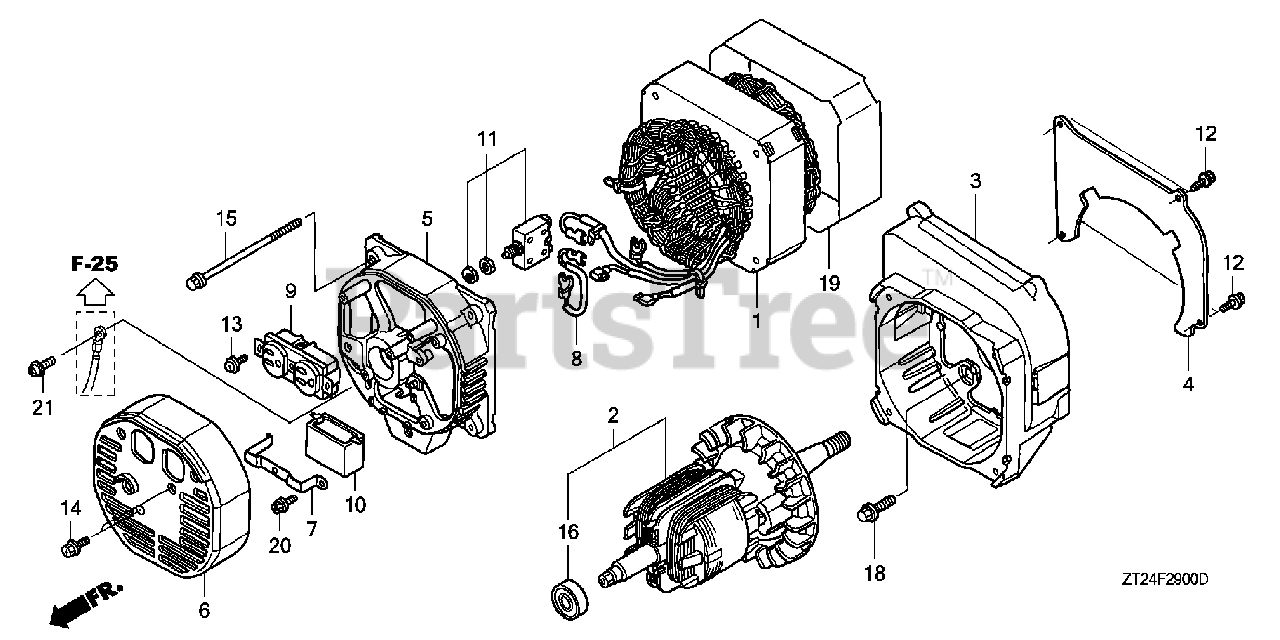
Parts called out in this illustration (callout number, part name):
1	STATOR ASSY.
3	HOUSING, FR.
4	PLATE, HOUSING
5	HOUSING, RR.
6	COVER, GENERATOR END
7	HOLDER, CONDENSER
8	WIRE, TERMINAL
9	RECEPTACLE (20A/125V)
10	CONDENSER (A)
11	PROTECTOR, CIRCUIT (20A)
12	SCREW, TAPPING (5X12)
13	SCREW, TAPPING (4X10)
14	SCREW, TAPPING (5X14)
15	BOLT, FLANGE (6X90)
16	BEARING ASSY. (6202DDUCE)
18	BOLT, GEN. SET
19	COVER, STATOR
20	SCREW, TAPPING (5X14)
21	SCREW, TAPPING (5X12) (GROUND CABLE)
21	SCREW, PAN (5X12) (GROUND CABLE)
